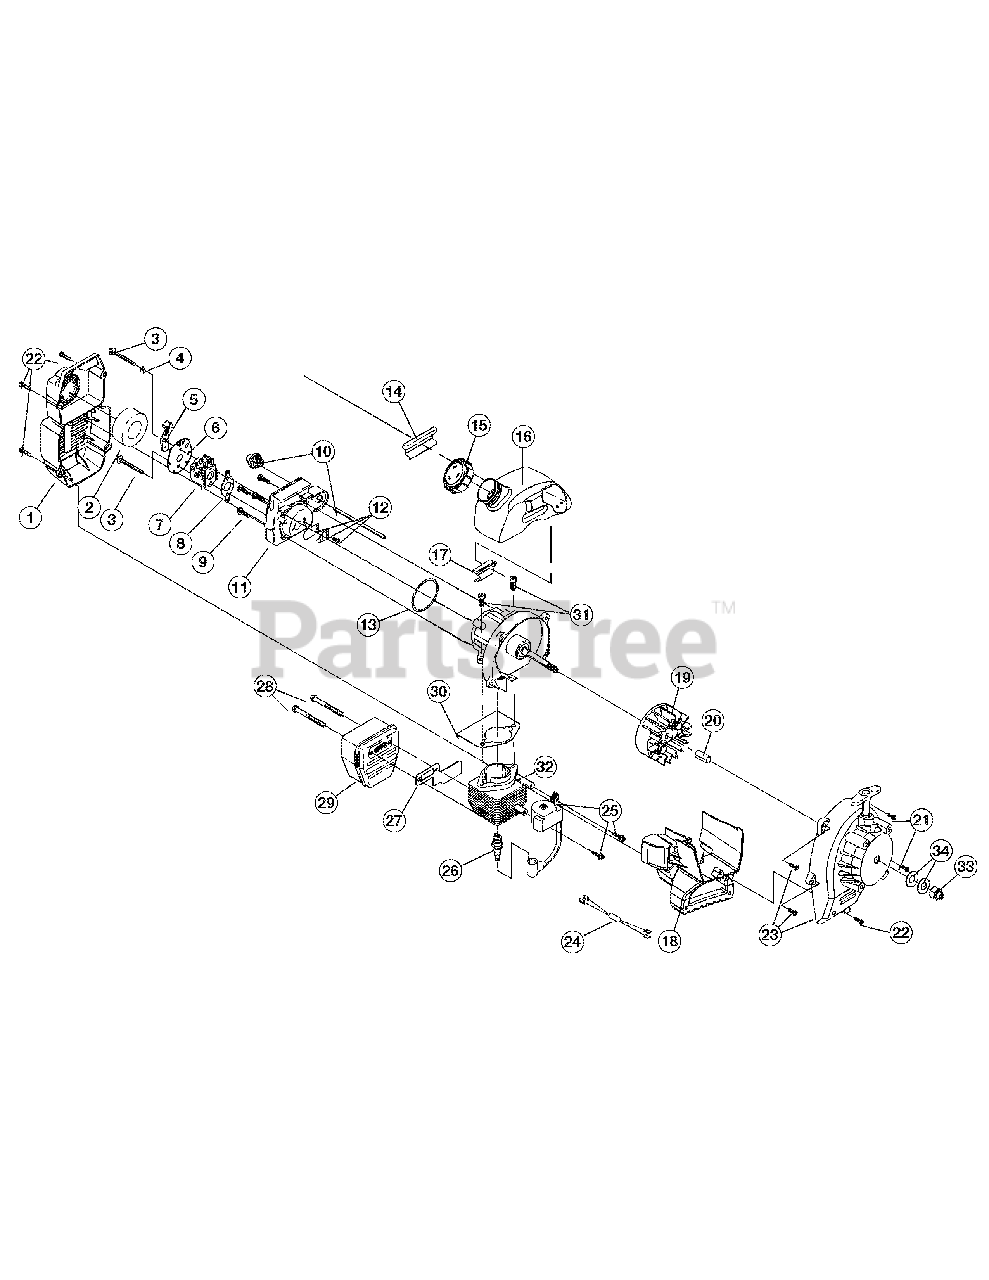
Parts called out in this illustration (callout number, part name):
1	Air Cleaner Cover Assembly
2	Air Cleaner Filter
3	Carburetor Mounting Screw
4	Wavey Washer
5	Choke Lever Assembly
6	Choke Plate Assembly
7	Carburetor Assembly
8	Carburetor Gasket
9	Carb Mount Screw
10	Primer and Hose Assembly
11	Carb Mount Assembly
12	Reed Assembly
13	O-Ring
14	Rear Mounting Pad
15	Fuel Cap Assembly
16	Fuel Tank Assembly
17	Front Mounting Pad
18	Shroud Extension
19	Flywheel Assembly
20	Spacer
21	Housing Screw
22	Cover Screw
23	Starter Housing Assembly
24	Wire Lead Assembly
25	Module Assembly
26	Spark Plug
27	Exhaust Gasket
28	Muffler Mounting Bolt Assembly
29	Muffler Assembly
30	Cylinder Gasket
31	Cylinder Bolt
32	Cylinder Assembly
33	Crankshaft Extension
34	Washer
